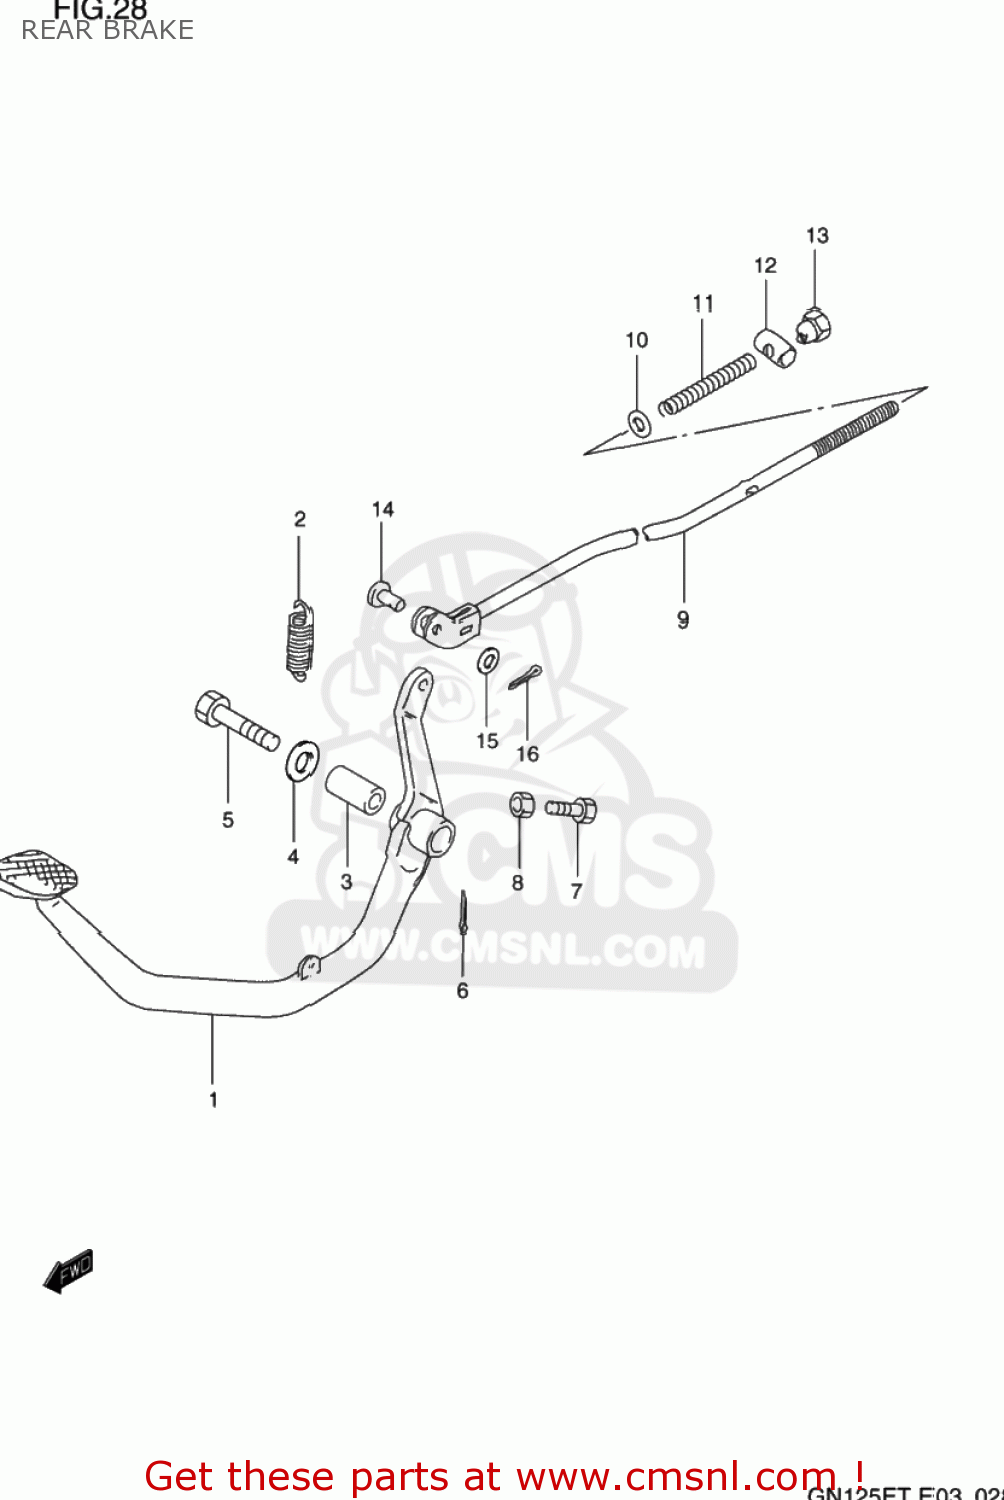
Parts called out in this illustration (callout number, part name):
1	PEDAL,BRAKE
2	SPRING
3	SPACER,BRAKE PEDAL BOSS
4	WASHER
5	BOLT 10X52
6	PIN 20X20
7	BOLT(6X23)
8	NUT
9	ROD ASSY,RR BRAKE
10	WASHER
11	SPRING
12	PIN(11X18)
13	NUT (6MM)
14	PIN(L:13.5)
15	WASHER
16	PIN 20X20
